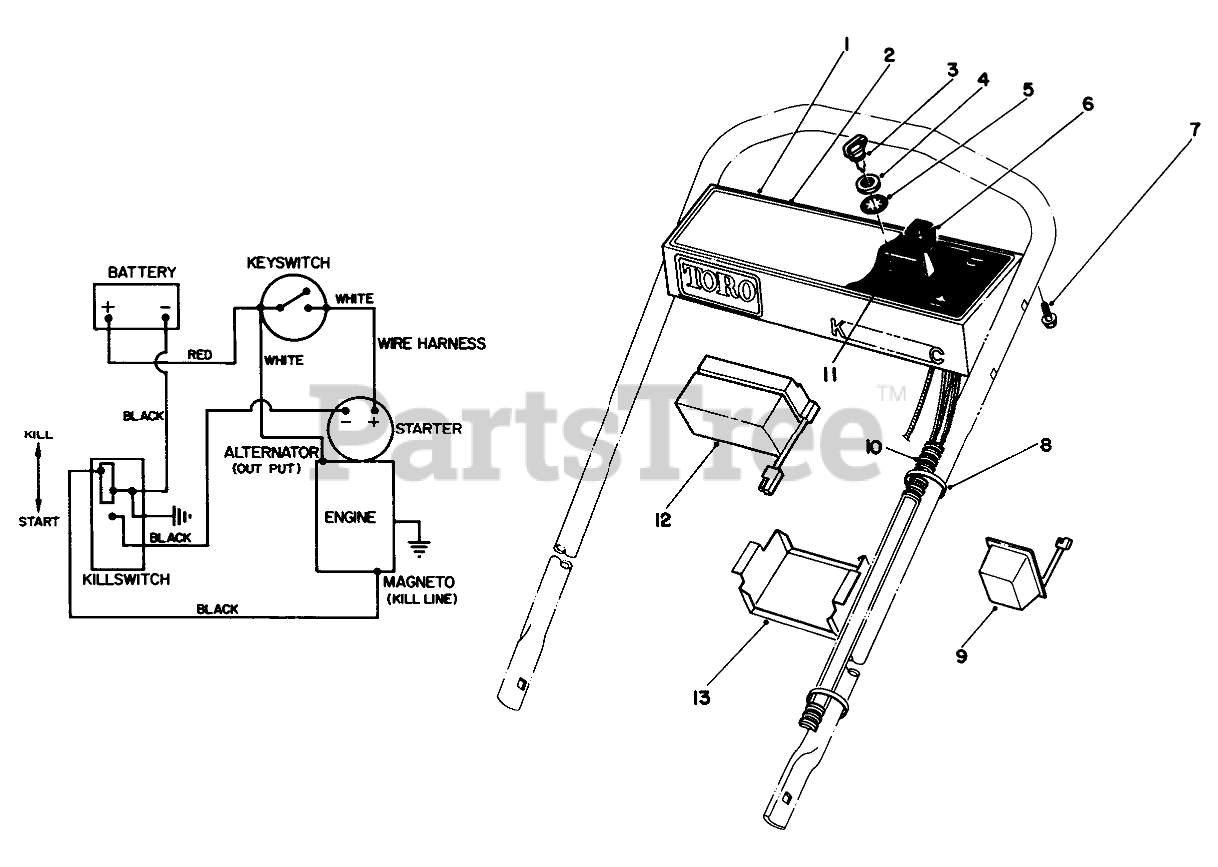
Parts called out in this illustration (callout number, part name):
1	Control Panel (Incl. Ref. #2)
2	Decal-Instructions
3	KEY-IGNITION
4	NUT-HH
5	WASHER-TOOTH, INTERNAL
6	THROTTLE CONTROL
7	SCREW-HWHTF
8	TIE-CABLE
9	Charger
10	WIRE HARNESS
11	Switch-Starter (Incl. Ref. #4 & 5)
12	Battery
13	BATTERY RETAINER
